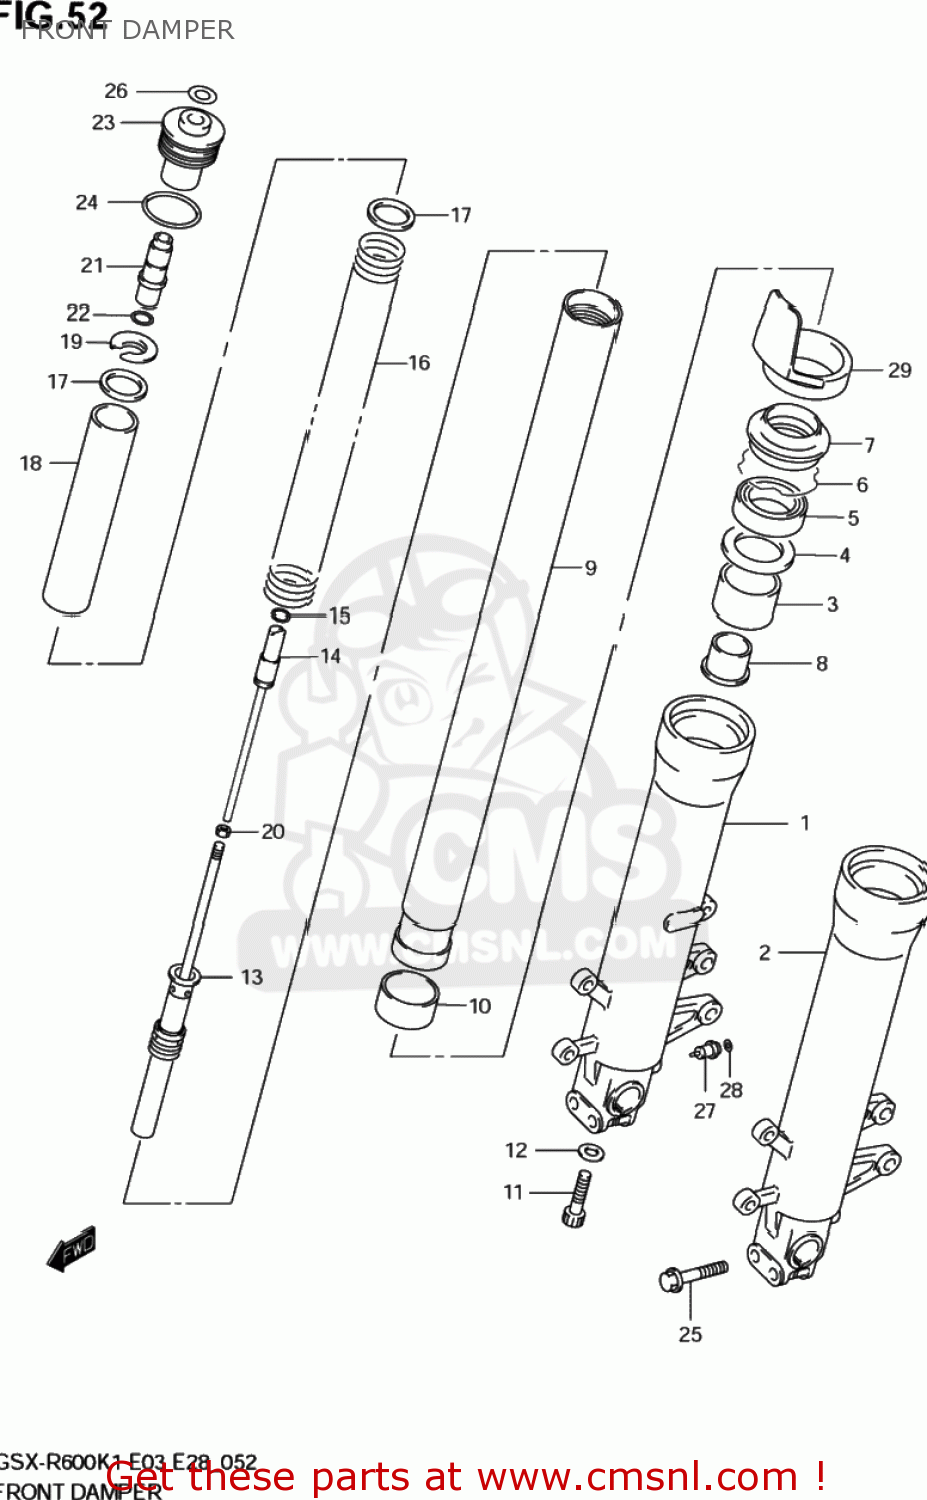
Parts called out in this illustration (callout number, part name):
1	TUBE,OUTER,R
2	TUBE,OUTER,L
3	BUSH,GUIDE
4	SPACER,SEAL
5	SEAL,OIL
6	RING,OIL SEAL STOPPER
7	SEAL,DUST
8	PIECE,OIL LOCK
9	TUBE,INNER
10	BUSH,SLIDE
11	BOLT
12	WASHER(10X15X1.5)
13	ROD,FR DAMPER
14	ROD,ADJUST
15	O RING(D:1.9,ID:3.8)
16	SPRING,FR
17	JOINT,SPRING
18	COLLAR,SPRING
19	SEAT,SPRING UPR
20	NUT
21	ADJUSTER,SPRING
22	O RING(D:2.5,ID:13.8)
23	BOLT,FORK
24	O RING
25	BOLT
26	LABEL
27	PIECE,ADJUST
28	LABEL,ADJUST PIECE LWR
29	PROTECTOR
